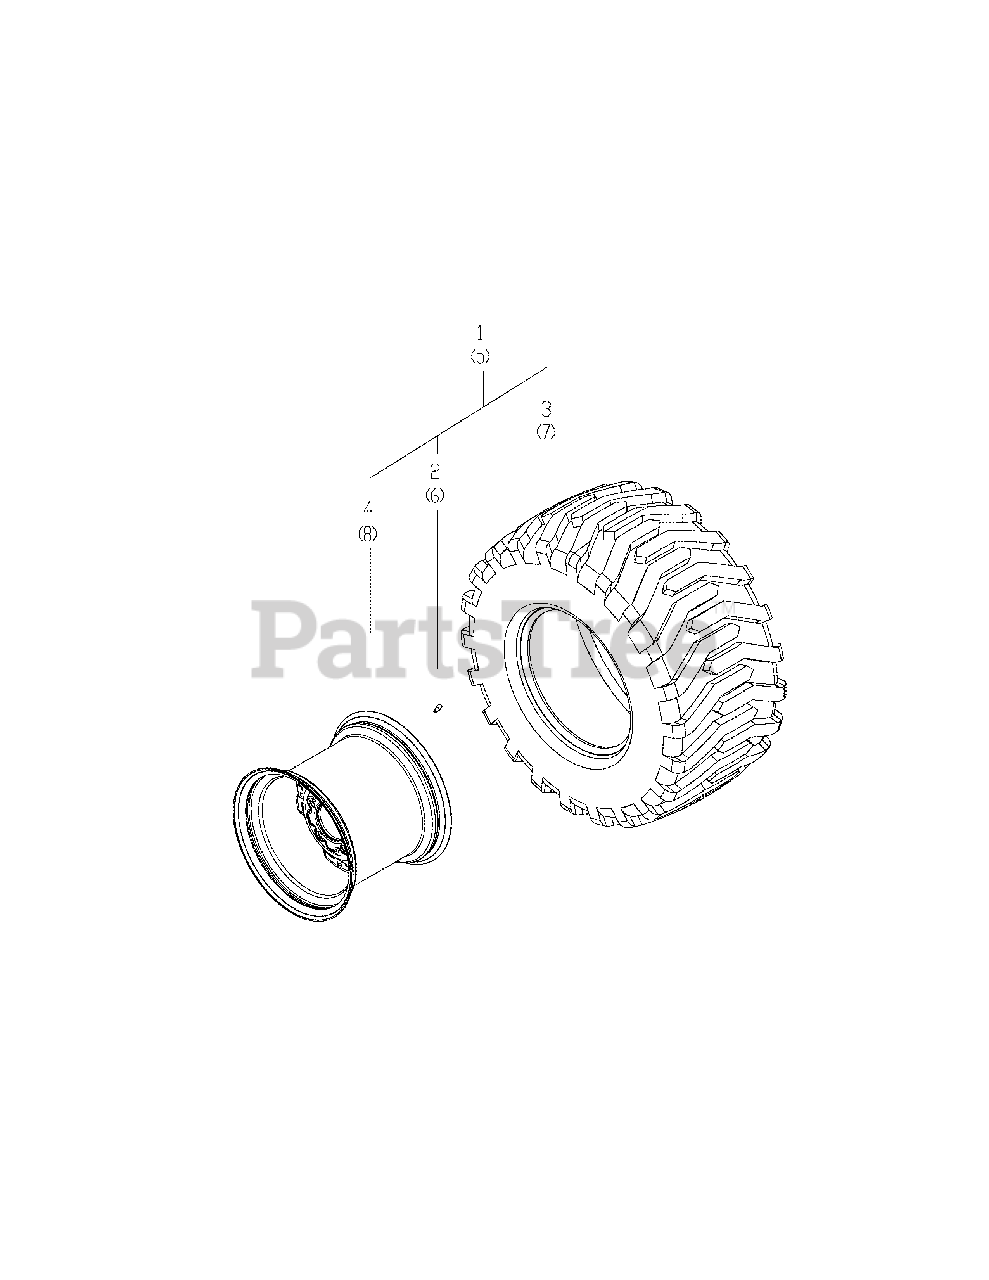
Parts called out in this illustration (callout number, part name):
1	R4 Rear Tire L Kit
3	Tire, 26X12-12 R4
5	R4 Rear Tire R Kit
7	Tire, 26X12-12 R4
